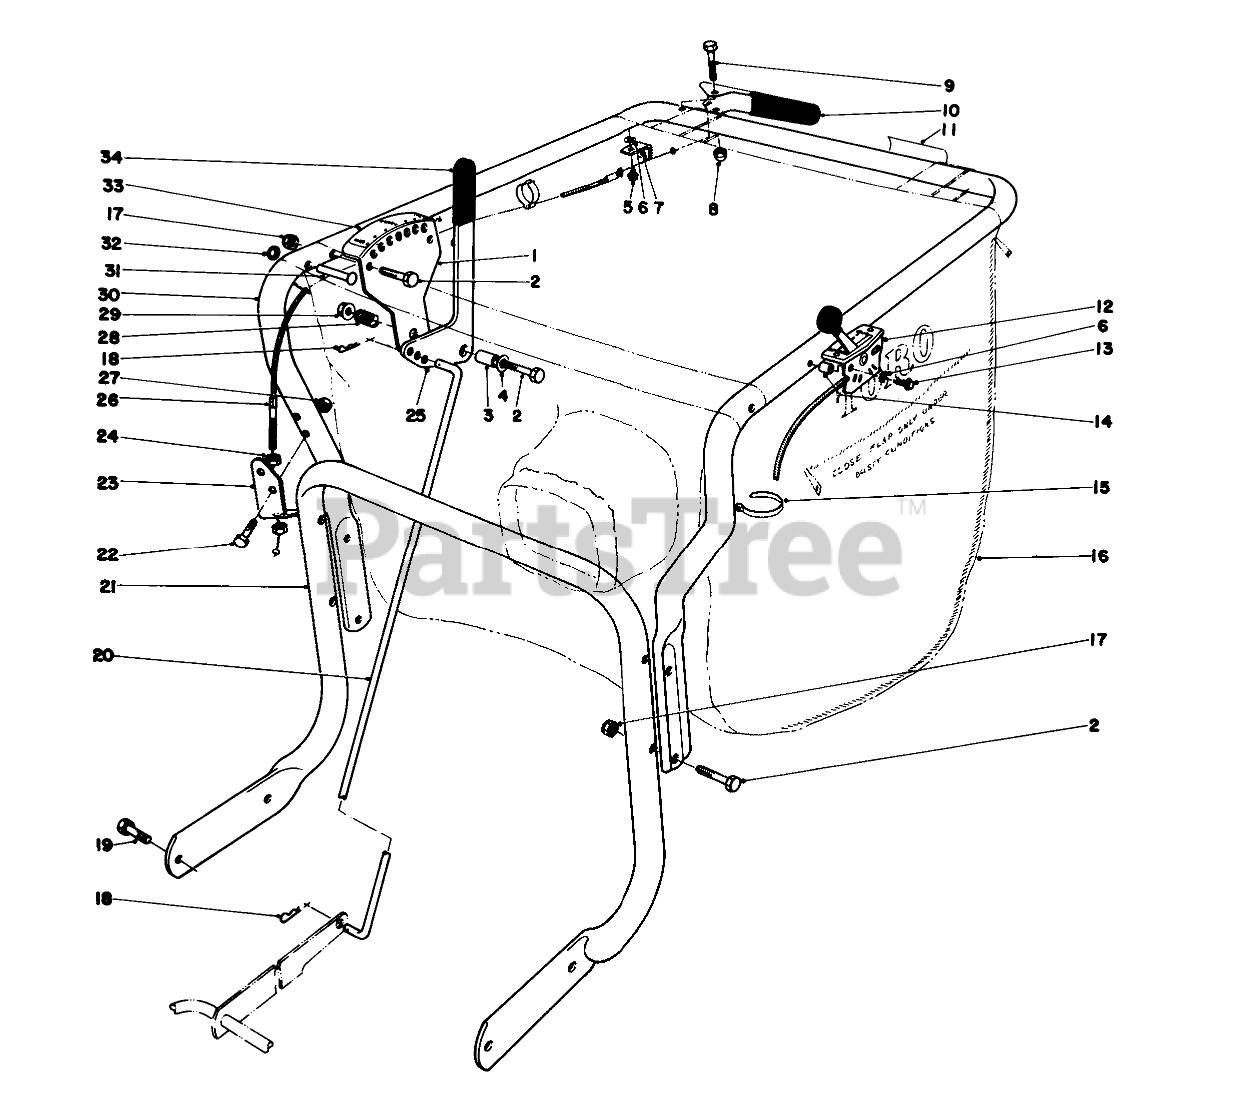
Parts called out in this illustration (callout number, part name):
1	Adjustment Bracket
2	SCREW-HH
3	SPACER
4	WASHER-FLAT
5	SCREW
6	WASHER-LOCK, EXT
7	RETAINING-CLIP
8	NUT-CAP
9	SCREW-HH
10	LEVER W/GRIP
11	TRACTION CONT DECAL
12	THROTTLE CONTROL
13	10-24 X 1 PAN HD SCR
14	SPACER
15	TIE-CABLE
16	Bag-Vacuum
17	NUT-LOCK, CONE
18	PIN-COTTER
19	SCREW-HH
20	HEIGHT ADJ. ROD
21	HANDLE
22	SCREW-HH
23	MOUNT-BOWDEN, LOWER
24	NUT-KEPS
25	Handle-Adjustment
26	FWD ASSY CABLE
27	NUT-LOCK, CONE
28	SPRING-COMPRESSION
29	NUT-HF
30	HANDLE-UPPER, VACUUM
31	RIVET
32	NUT-PUSH IN
33	HT ADJ DECAL
34	GRIP-HANDLE
